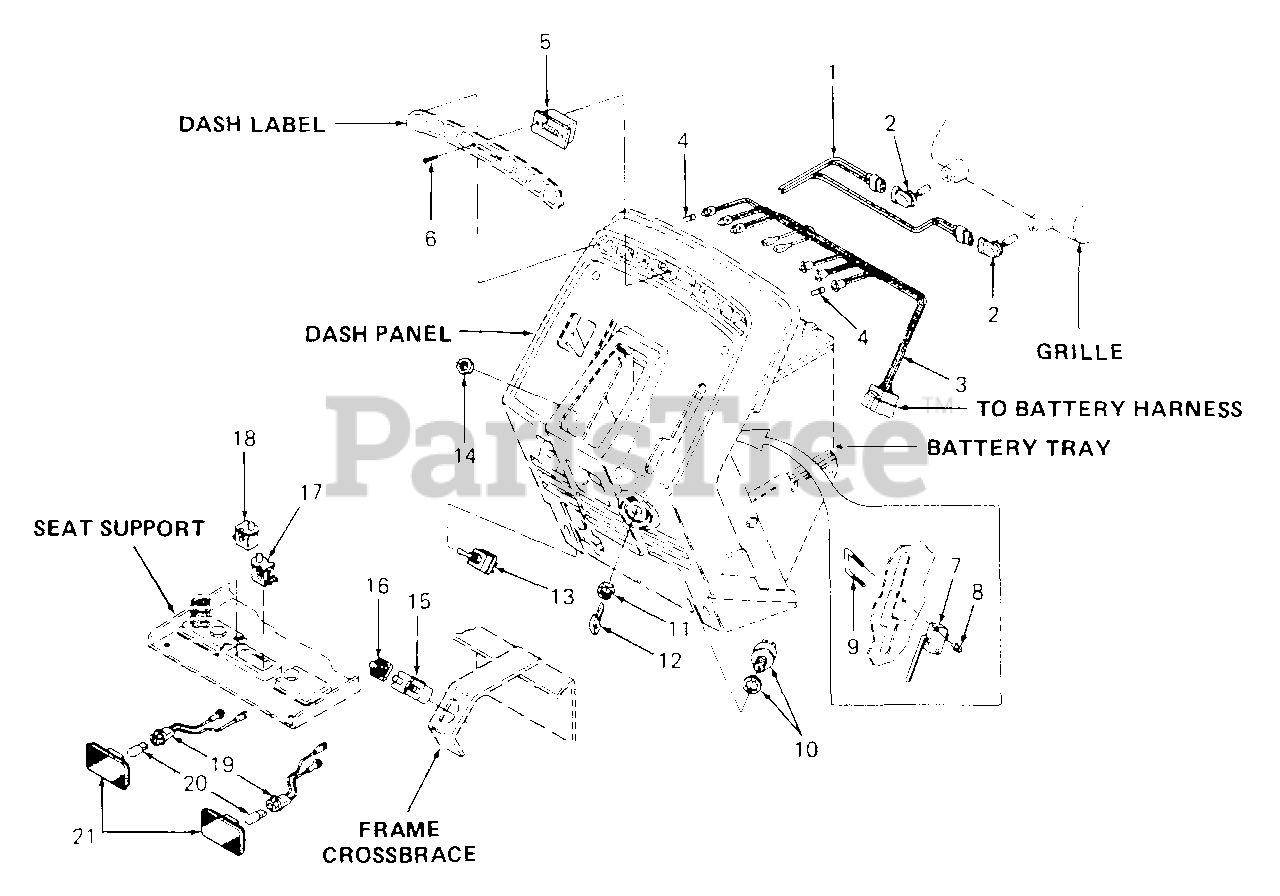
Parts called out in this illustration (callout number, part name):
1	Harness, Main Wire
2	Bulb, Head Lamp
3	Harness, Indicator Wire
4	Bulb, Indicator
5	Hour Meter
6	Screw, Truss Hd Tapp, #6 x .62 Lg
7	Switch, Reverse
8	Nut, Hex Insert Lock, #4-40
9	Screw, Switch
10	Switch, Ignition
11	Nut, Ignition Switch
12	Key, Ignition, Set of 2
13	Switch, PTO
14	Nut, Hex, 1/2-27 x .100 Thk
15	Switch, Interlock
16	Boot, Switch
17	Switch, Snap Mount (Grey)
18	Switch, Snap Mount (Black)
19	Cable Assy, Tail Light
20	Bulb, Tail Light
21	Lens Assy, Tail Light
